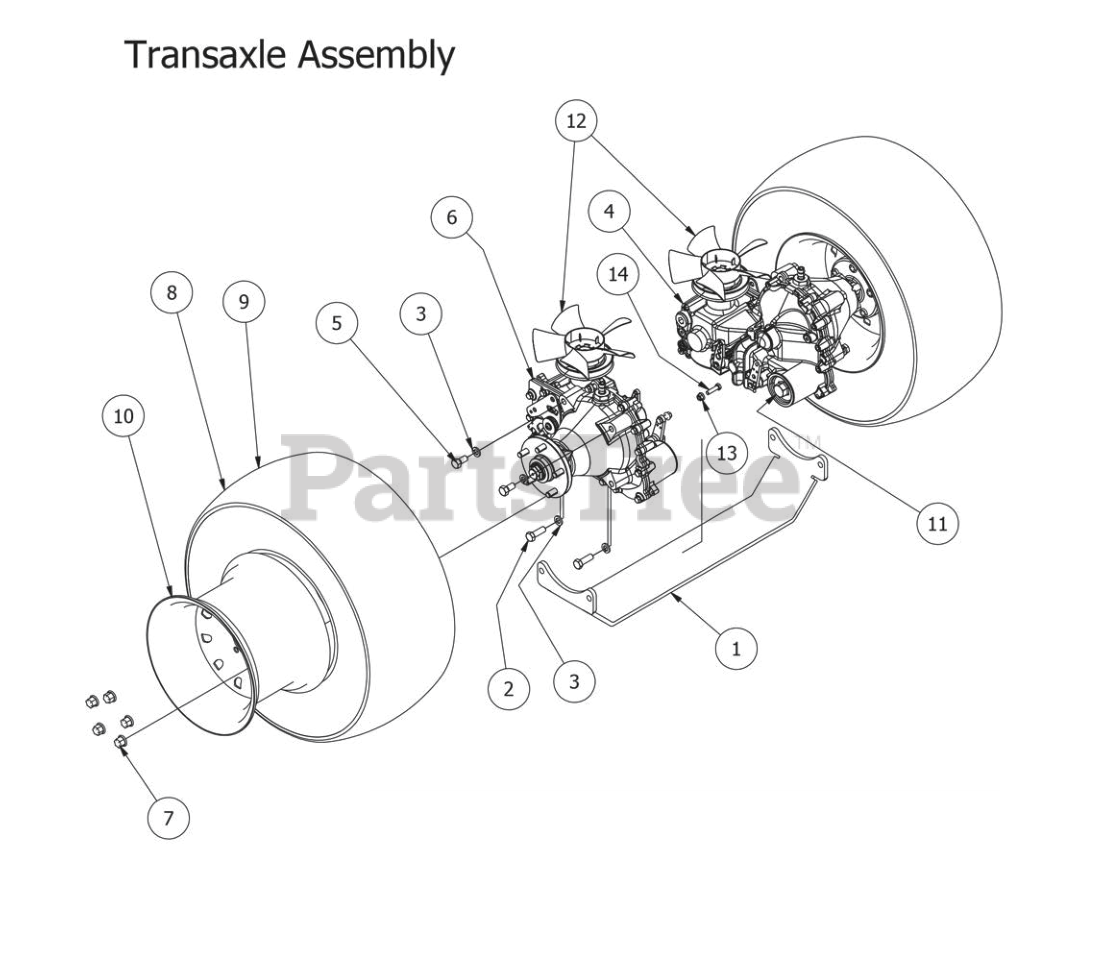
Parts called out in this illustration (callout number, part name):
1	Outlaw Transaxle Cross Brace
2	1/2" x 1 1/2" Hex Bolt
3	1/2" Lock Washer
4	ZT-5400 - Right
5	1/2" x 1" Hex Bolt
6	ZT-5400- Left
7	Acorn Lug Nut
8	24 x 12.00-10 Tire and Wheel assembly
9	24 x 12.00 10 outlaw Tire
10	10" Wheel For Outlaw
11	Hydro Filter for Outlaw
12	Fan/Pulley Kit for Outlaw
13	5/16" Nylon Flange Nut
14	5/16 x 1 1/4 Hex Bolt
